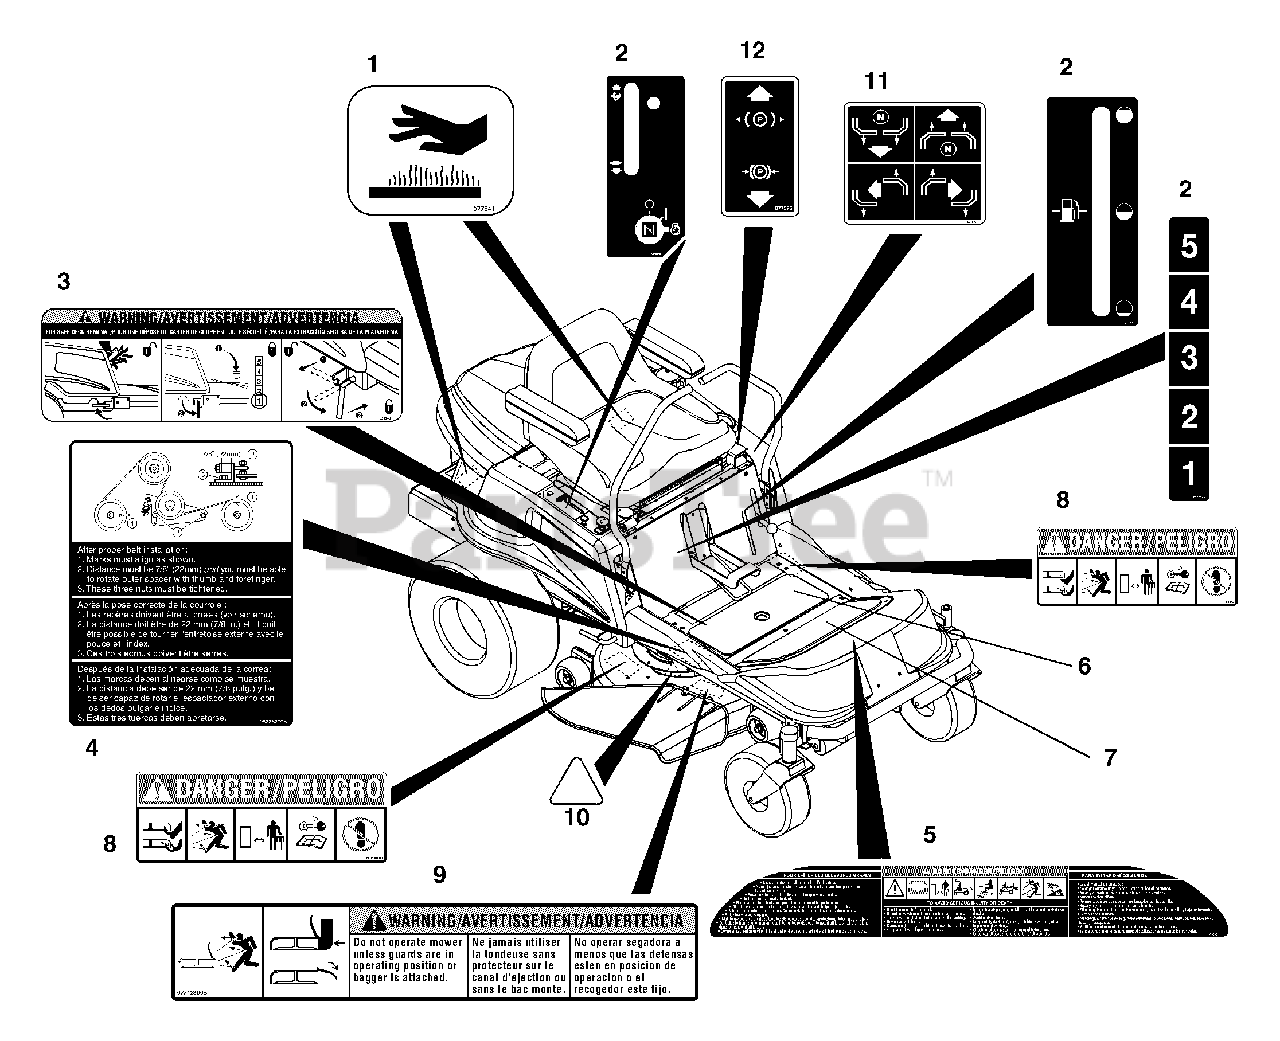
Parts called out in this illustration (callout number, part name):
1	Decal, Hot Surface
2	Decal-Instructional Set
3	Decal, Safe Deck Removal
4	Decal, Belt Diagram
5	Decal, Bilingual Danger
6	Non-Skid Cover
7	Non-Skid Cover
8	Decal, Mower Pan Head Danger
9	Decal, Warning
10	Decal, Blade Alignment
11	Decal, Instructional - Steering
12	Decal, Parking Brake Lever
